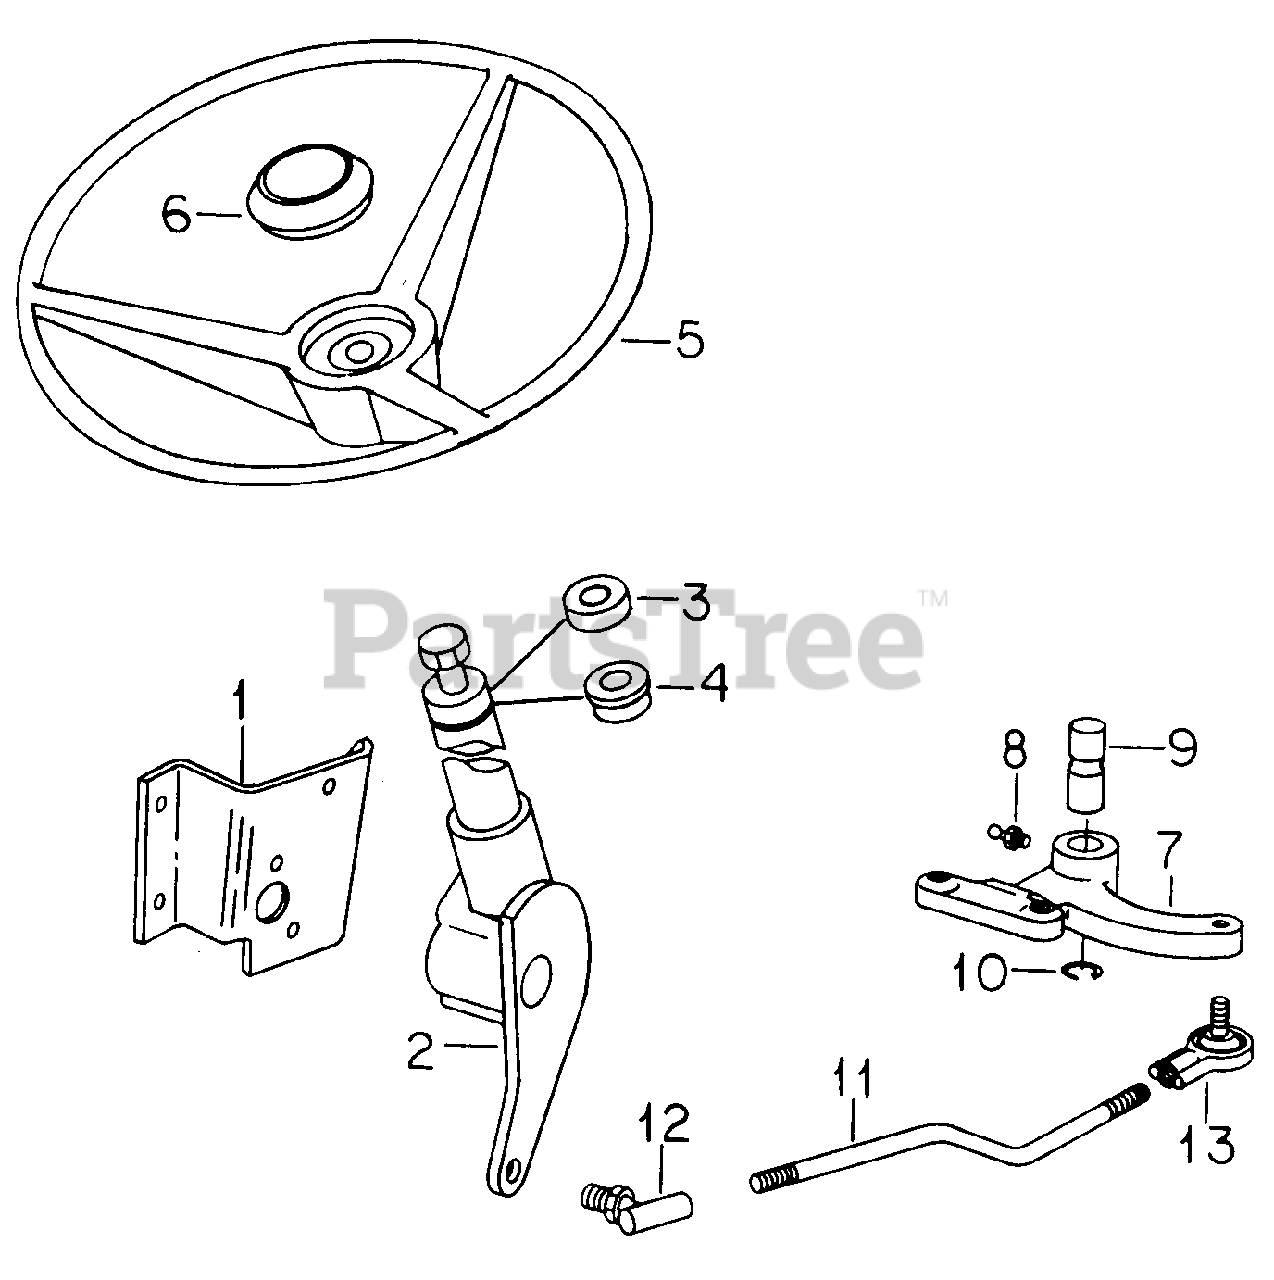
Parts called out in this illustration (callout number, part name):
1	Bracket, Steering Gear Support
2	Gear Assy, Steering
3	Seal, Steering Gear
4	Bearing, Column Upper
5	Wheel, Steering
6	Cap, Steering Wheel
7	Lever, Steering
8	Fitting, Lube
9	Pin, Steering Pivot
10	Ring, Retaining
11	Link, Drag
12	Joint, Ball
13	Joint, Ball
